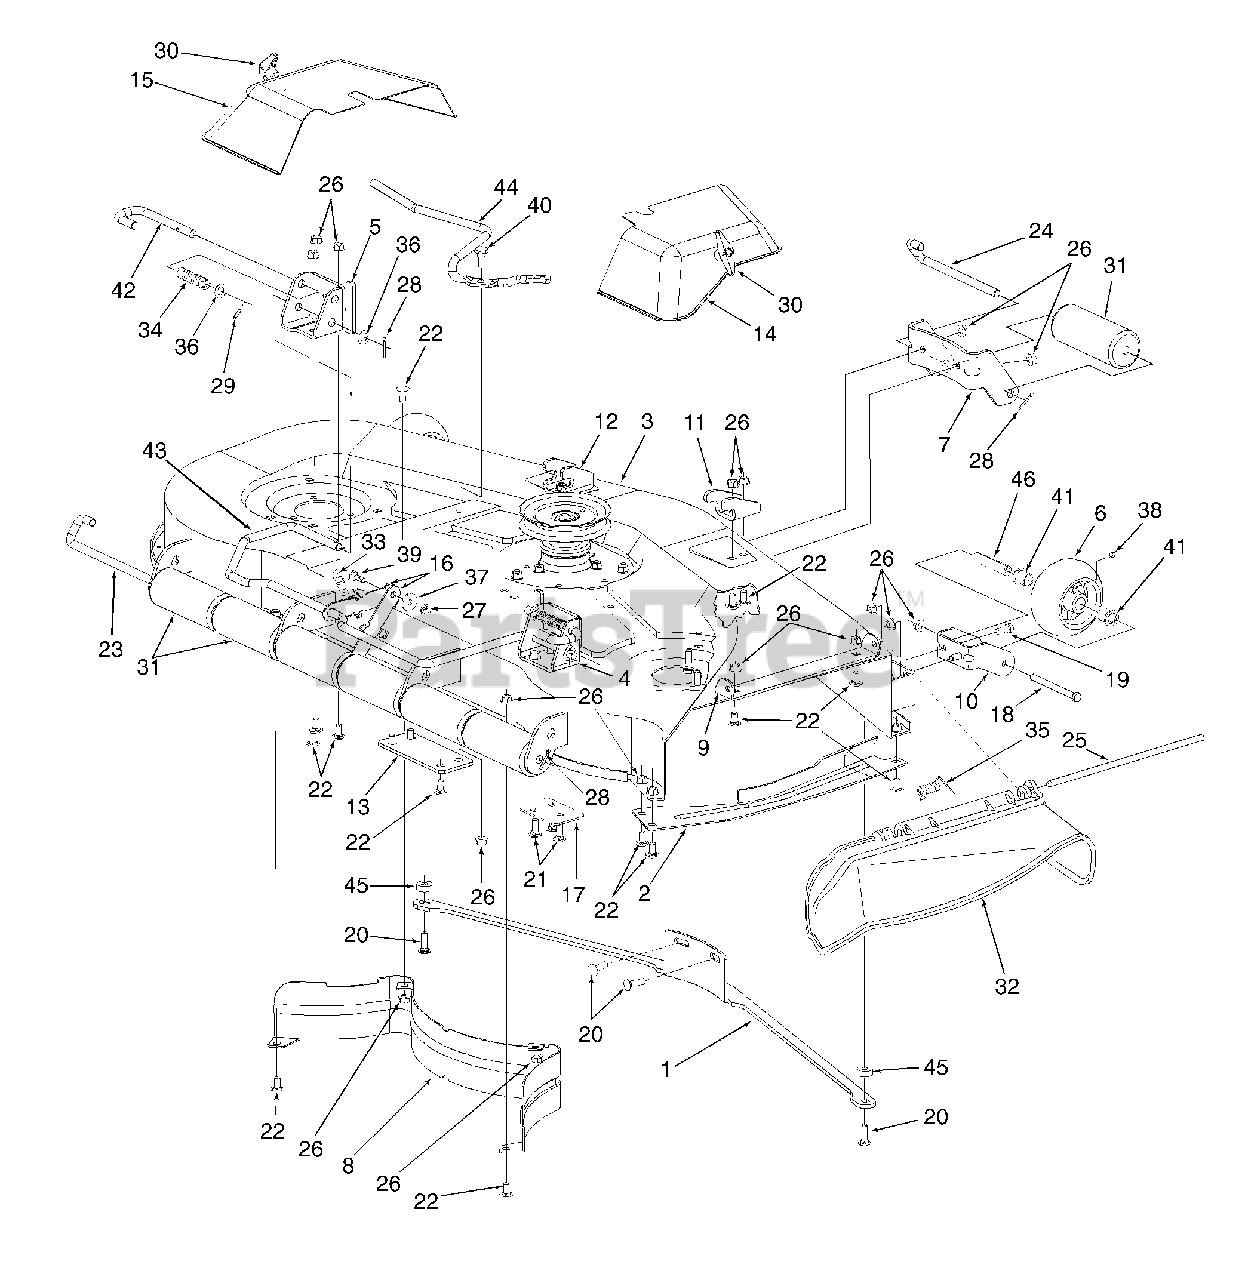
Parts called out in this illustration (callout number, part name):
3	Housing Ass'y, 54" Mower Deck
4	Bracket, Rear Hanger RH
5	Bracket, Rear Hanger LH
6	Wheel Ass'y, 5" Deck
7	Bracket, Front Roller
10	Bracket, Deck Wheel
11	Bracket, Front Deck - RH
12	Bracket, Front Deck - LH
15	Cover, Belt - LH
16	Link, Deck Support
19	Screw, Hex Cap, 3/8-16 x .88 GR5
20	Bolt, Carriage, 3/8-16 x 1.25 GR5
21	Bolt, Carriage, 3/8-16 x 1.0 GR5
22	Bolt, Carriage, 3/8-16 x .75 GR5
24	Pin, Roller, 1/2 x 7.31
26	Nut, Hex Flange Lock, 3/8-16
27	Nut, Hex Flange Lock, 5/16-18
28	Pin, Cotter 1/8 x 1.0
29	Pin, Spirol Spring, 3/16 x 3/4
30	Knob, Wingnut, 5/16-18
31	Roller, Front & Rear
32	Deflector, Plastic Chute
33	Spring, Extension
34	Spring, Compression
35	Spring, Torsion
36	Washer, Flat, .536 x .93 x .05
37	Washer, Flat, .344 x 1.125 x .12
38	Grease Fitting
39	Bolt, Shoulder, .437 x .268:5/16-18
40	Bolt, Shoulder, .50 x .267:3/8-16
41	Bearing, Flange
42	Pin, Mower Support
43	Rod, Deck Support
44	Rod, Idler Spring Mtg
45	Spacer, .406 x 1.0 x .38
46	Spacer, Wheel
